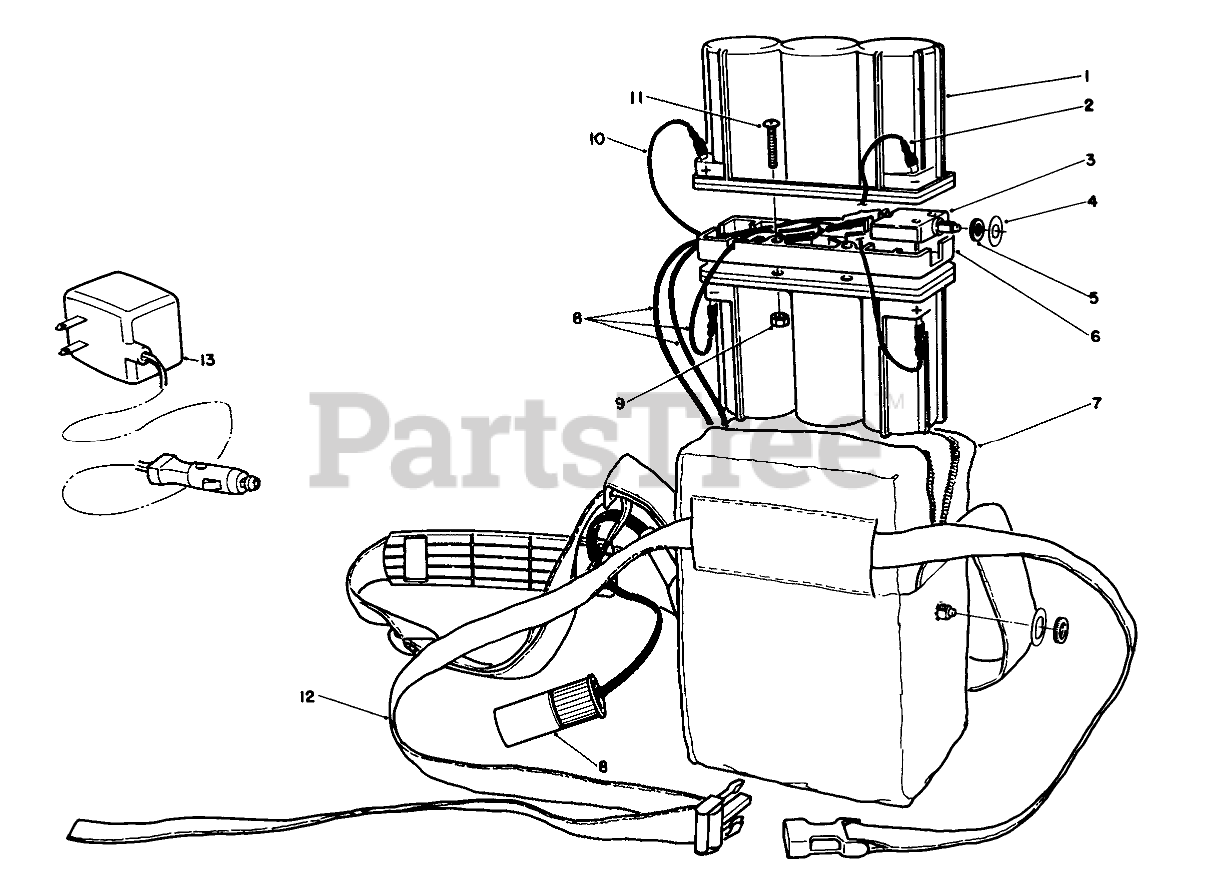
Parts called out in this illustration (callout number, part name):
1	BATTERY, 6 VOLT
2	WIRE ASSEMBLY-BATTERY
3	CKT BREAKER 15 AMP 125V
4	CIRCUIT BREAKER PLATE
5	KNURLED NUT
6	BATTERY SPACER
7	Pack-Soft
8	CORD-BATTERY PACK
9	NUT-HEX
10	WIRE ASSY-CIRCUIT BREAK
11	SCREW-PPH
12	BELT-WAIST
13	Charger 12 Volt
